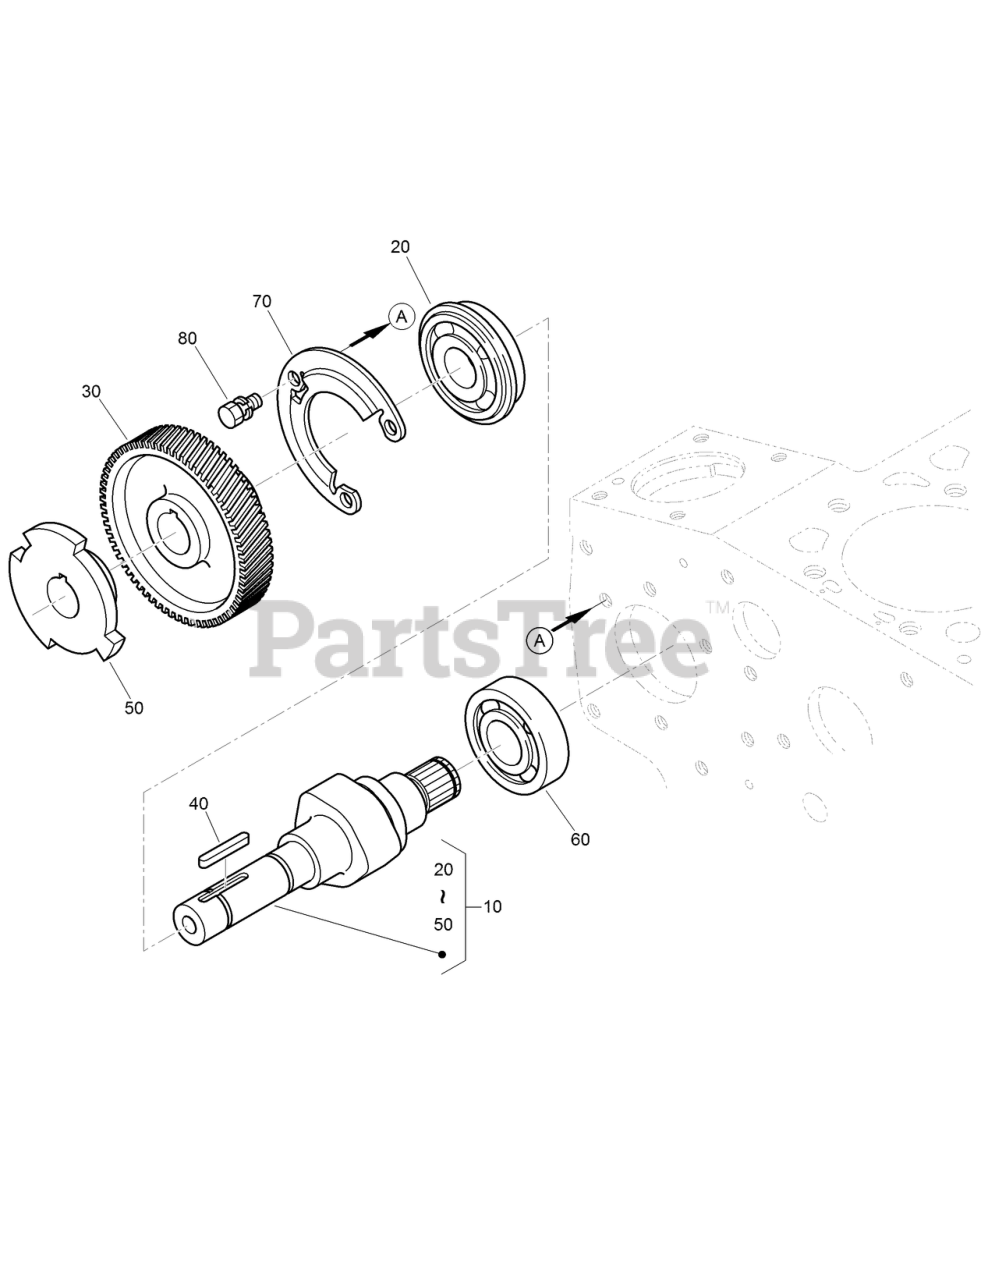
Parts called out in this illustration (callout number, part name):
10	FUEL CAMSHAFT ASM
20	BEARING-BALL
40	KEY-FEATHER
60	BEARING-BALL
70	STOPPER-CAMSHAFT, FUEL
